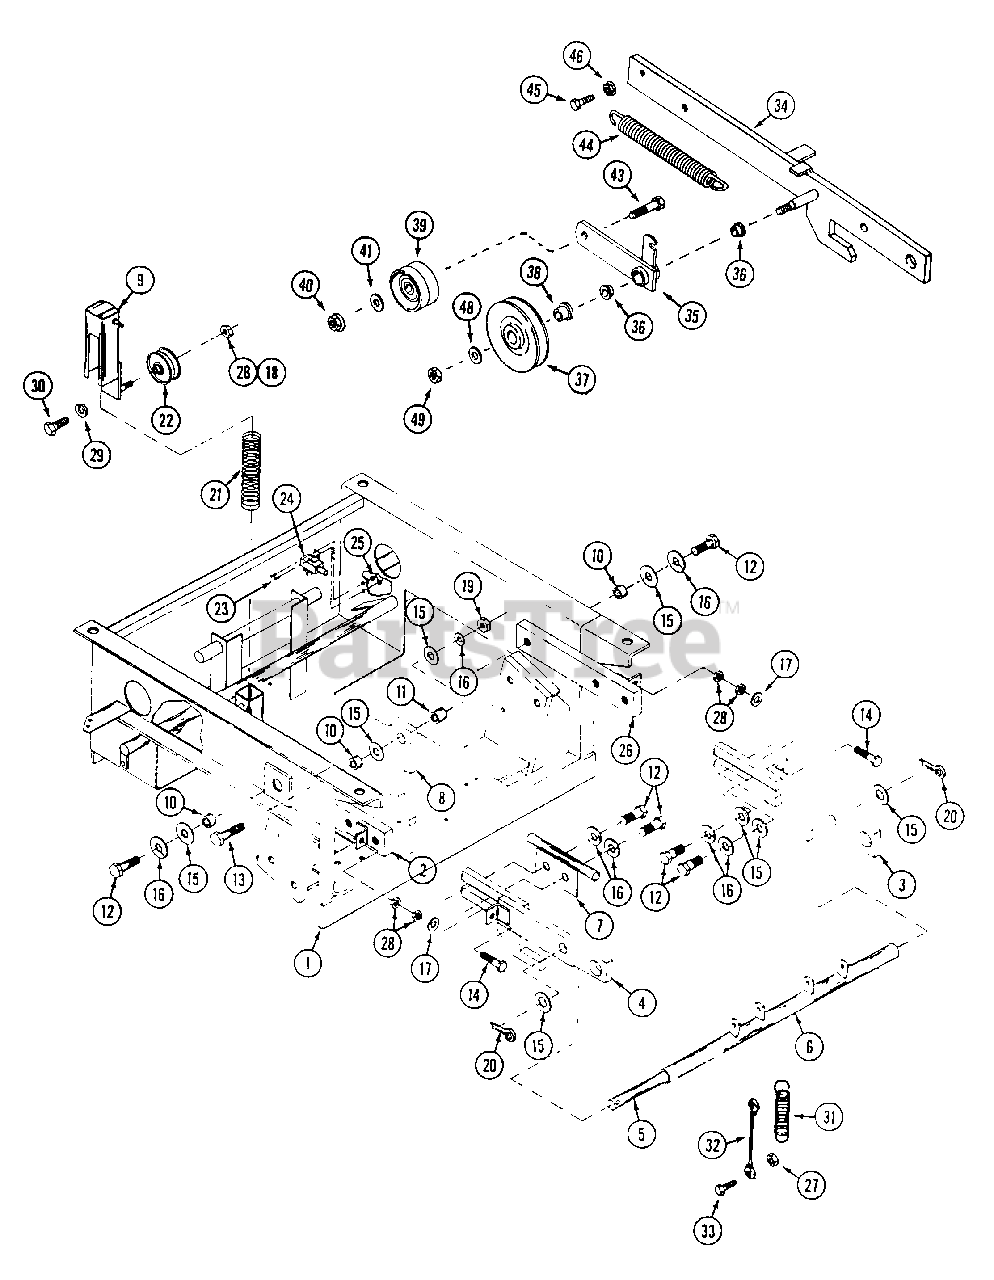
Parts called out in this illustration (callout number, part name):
1	BASE - 5018
5	PIN - cross bar
8	LOCK - forward nose down
9	TUBE - drive idler
10	BUSHING - deck lift arm (3/8" long)
11	BUSHING - pivot (1/2" long)
12	BOLT - 1/2" - 13 x 1-1/4"
13	BOLT - 1/2" - 13 x 2-1/4"
14	BOLT - 3/8" - 16 x 3"
15	WASHER - 1/2"
16	LOCKWASHER - 1/2"
17	WASHER - 3/8"
18	NUT - flange lock 3/8" - 16
19	NUT 1/2" - 13
20	PIN - cotter 1/8" x 1"
21	SPRING - idler tension
22	PULLEY - idler 2-1/4" O.D.
23	SCREW - machine #10 - 32 x 5/8"
24	SWITCH - safety
25	NUT lock #10 - 32
26	ARM - deck lift L.H. (1800)
27	NUT - lock 1/4" - 20
28	NUT - 3/8" - 16
29	LOCKWASHER - 3/8"
30	BOLT - 3/8" - 16 x 2-1/2"
31	SPRING - lift assist
33	BOLT - 1/4" - 20 x 1"
34	ARM - deck L.H.
34	ARM - deck R.H.
36	BUSHING - flange
37	PULLEY - "V" idler
38	BUSHING - pulley
39	PULLEY - flat
40	NUT - 3/8" - 16 flange lock
41	WASHER - 3/8"
43	BOLT - 3/8" - 16 x 2"
44	SPRING - extension
45	BOLT - 5/16" - 18 x 1"
46	NUT - 5/16" - 18 flange lock
48	WASHER - 1/2"
49	NUT - 1/2" - 13 lock
